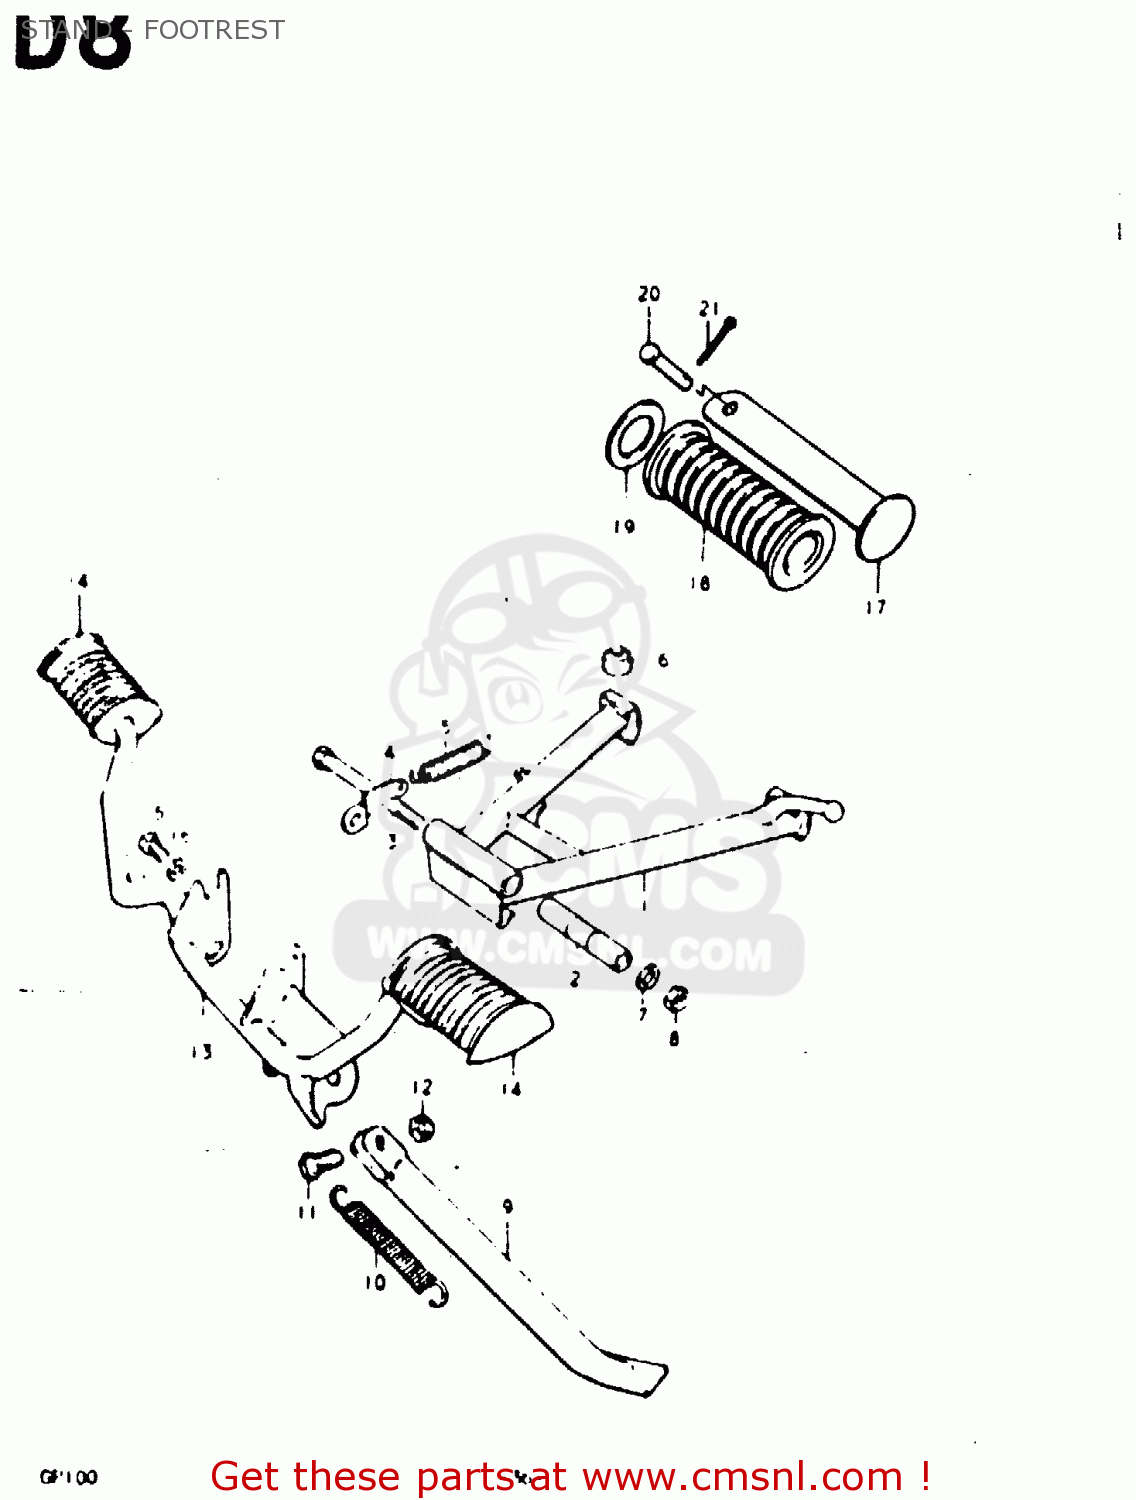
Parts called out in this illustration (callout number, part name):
1	STAND,CENTER
2	SPACER
3	BOLT(10X110)
4	HOOK,CTR STAND SPRING
5	SPRING
6	CUSHION
7	LOCK WASHER
8	NUT
9	STAND,PROP
10	SPRING
11	BOLT
12	NUT
13	BAR, FRONT FOOTREST
14	RUBBER,FR FOOTREST
15	BOLT
16	LOCK WASHER
17	BAR,FOOTREST RUBBER
18	RUBBER
19	WASHER (19.5X32X2)
20	PIN
21	PIN 20X20
